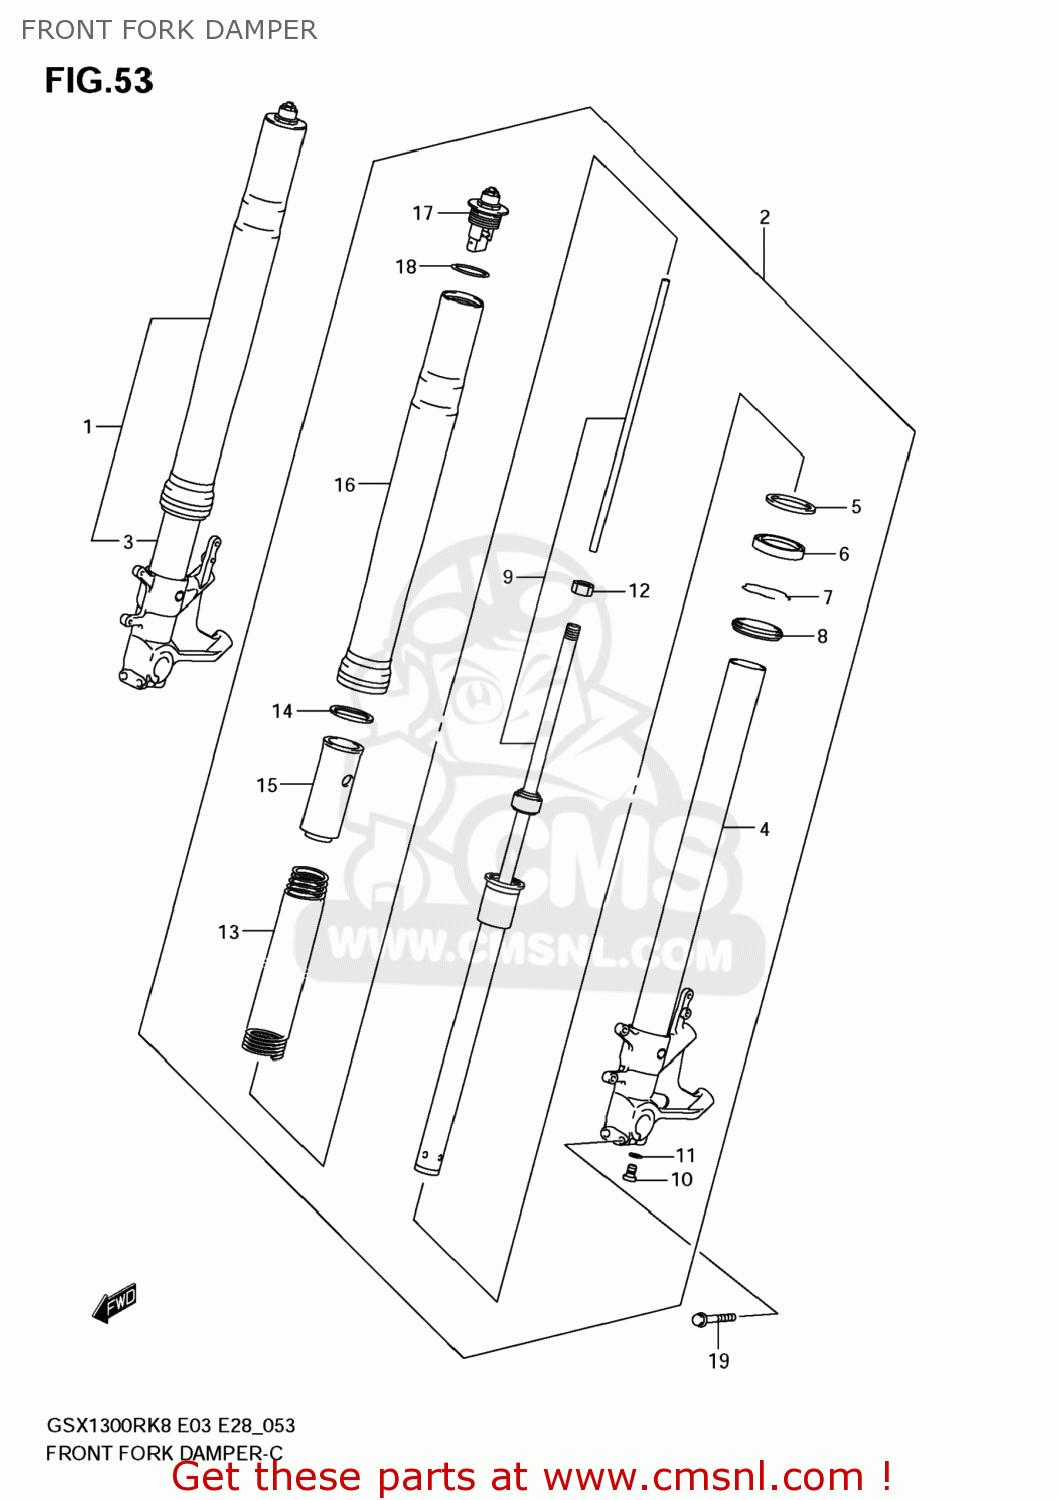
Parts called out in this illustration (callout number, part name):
1	DAMPER ASSY,FR FORK,R
2	DAMPER ASSY,FR FORK,L
3	TUBE,INNER,R
4	TUBE,INNER,L
5	WASHER
6	SEAL,OIL
7	RING,STOPPER
8	SEAL,DUST
9	CYLINDER
10	BOLT
11	GASKET (NAS)
12	NUT,ROD
13	SPRING,FR
14	GUIDE,SPRING
15	SPACER,SPRING
16	TUBE,OUTER
17	CAP,FR FORK
18	O RING
19	BOLT
